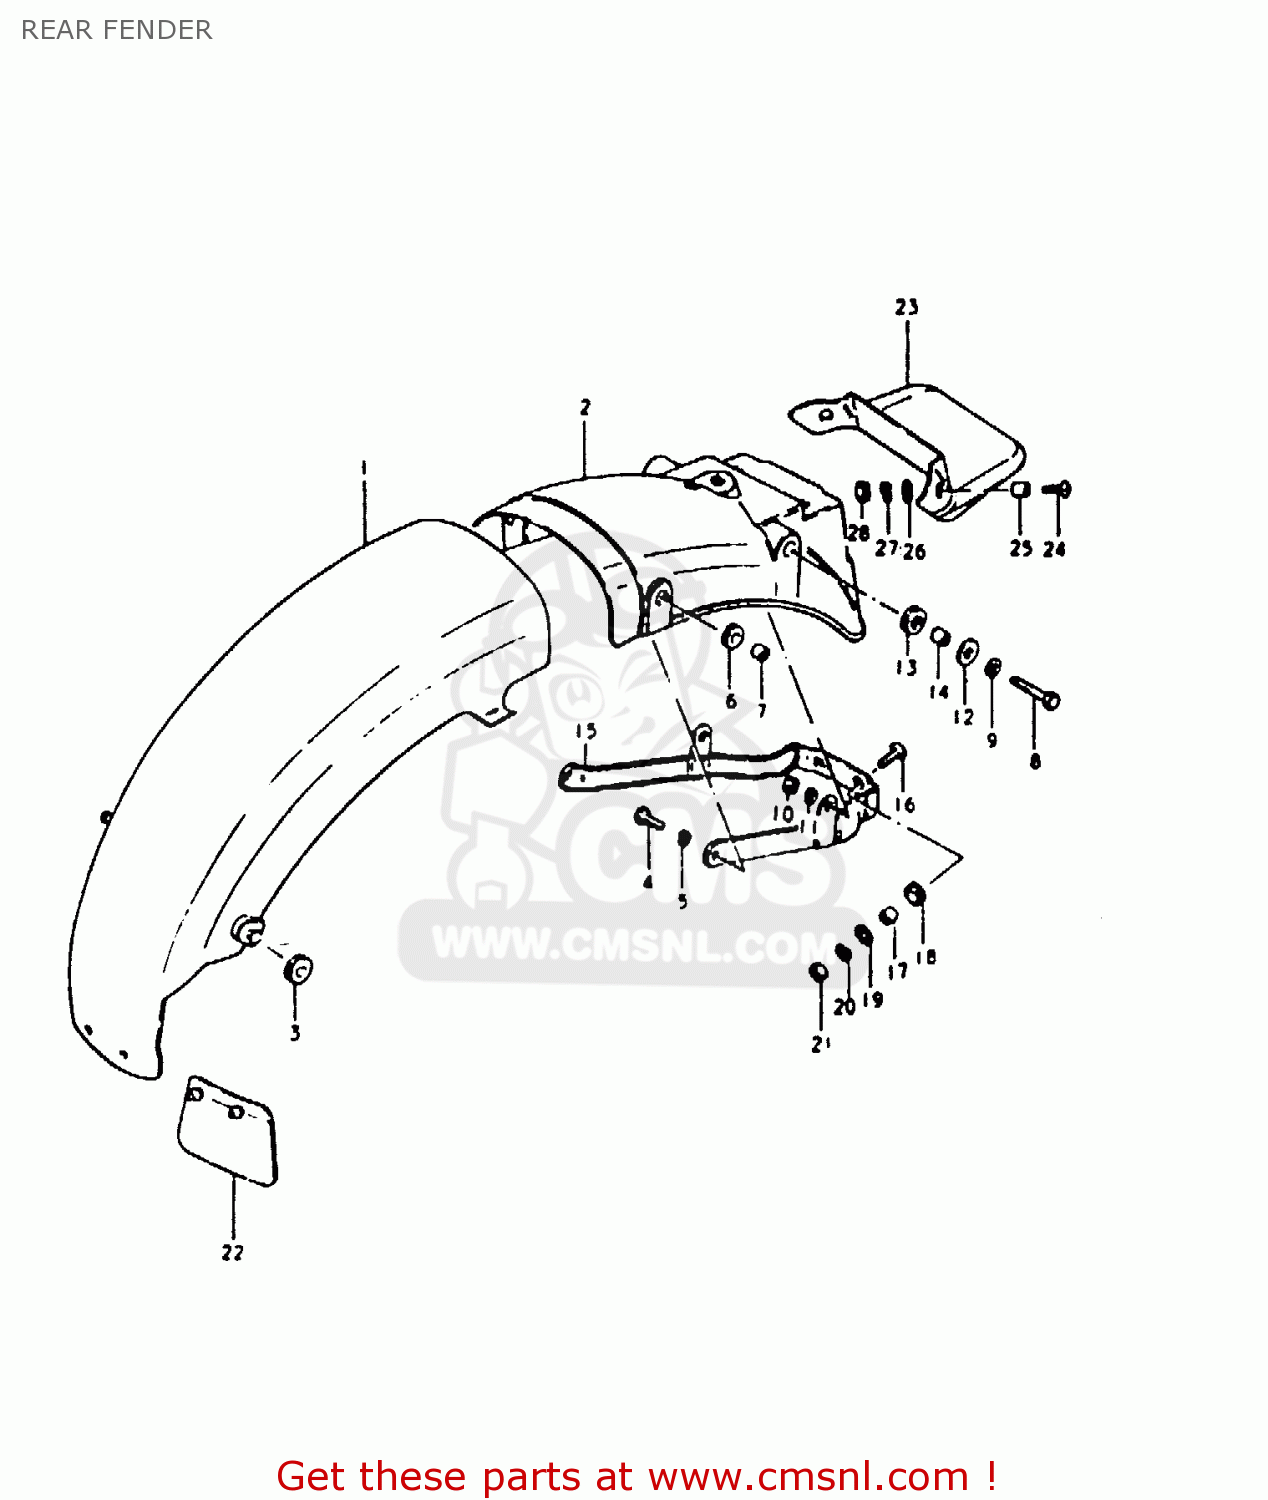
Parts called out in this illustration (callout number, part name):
1	FENDER,REAR
2	BODY,RR FENDER RR
3	CUSHION
4	BOLT
5	LOCK WASHER
6	CUSHION
7	SPACER(6.1X9X7.5)
8	BOLT
9	WASHER
10	NUT
11	LOCK WASHER
12	WASHER(8.5X26X1.2)
13	CUSHION
14	SPACER (8.2X12X7.5)
15	REINFORCEMENT,REAR FENDER
16	SCREW
17	SPACER (6.1X9X9)
18	CUSHION
19	WASHER(6,5X22X1.6)
20	LOCK WASHER
21	NUT
22	GUIDE,RR FENDER MUD
23	EXTENSION,REAR FENDER
24	SCREW (6X15)
25	SPACER(6.2X8.3X5.7)
26	WASHER(6.5X18X1)
27	LOCK WASHER
28	NUT
